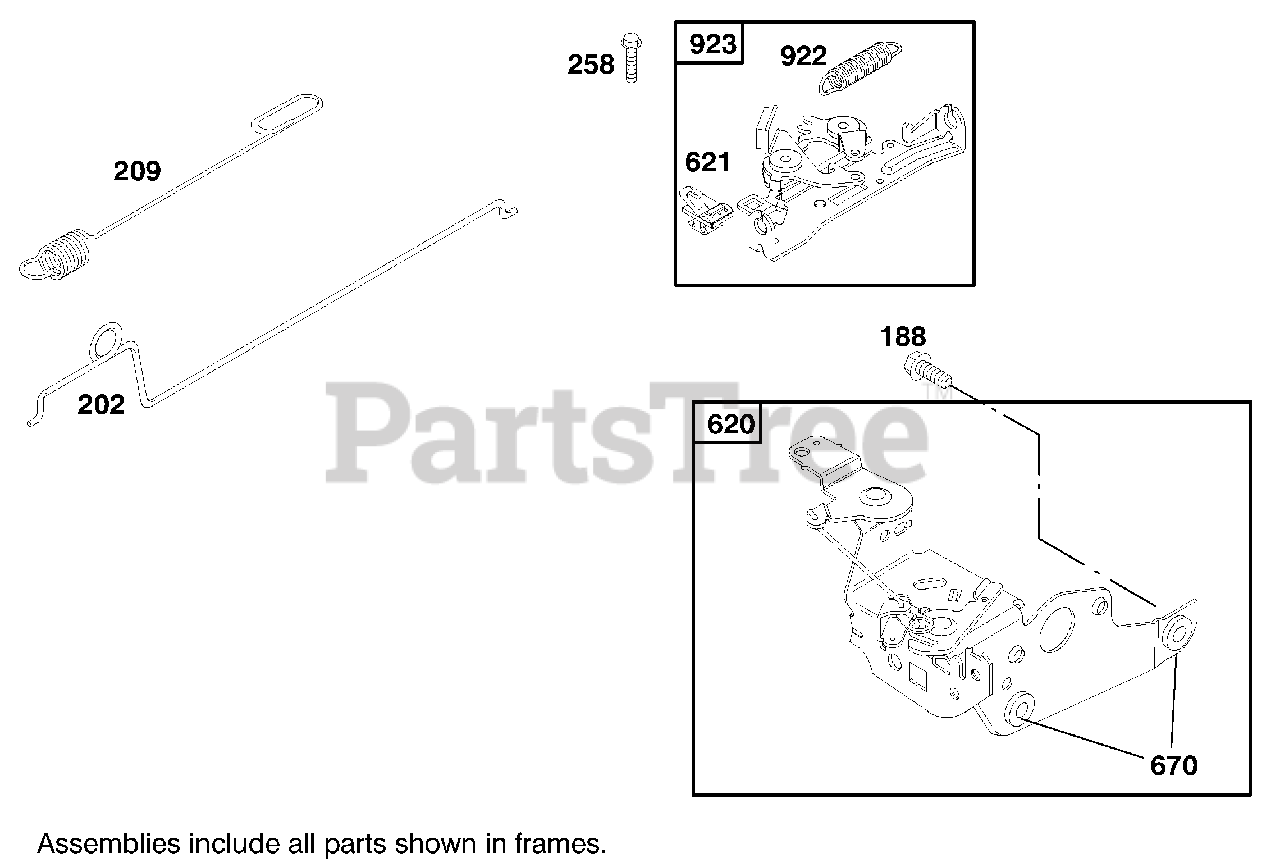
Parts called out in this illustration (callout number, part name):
188	Screw-Hex.
202	Link-Governor
209	Spring-Governor
258	Screw-Hex. Head
620	Bracket-Carburetor
621	Switch-Stop
670	Spacer-Bracket (Includes 2)
922	Spring-Brake
923	Brake Assembly
